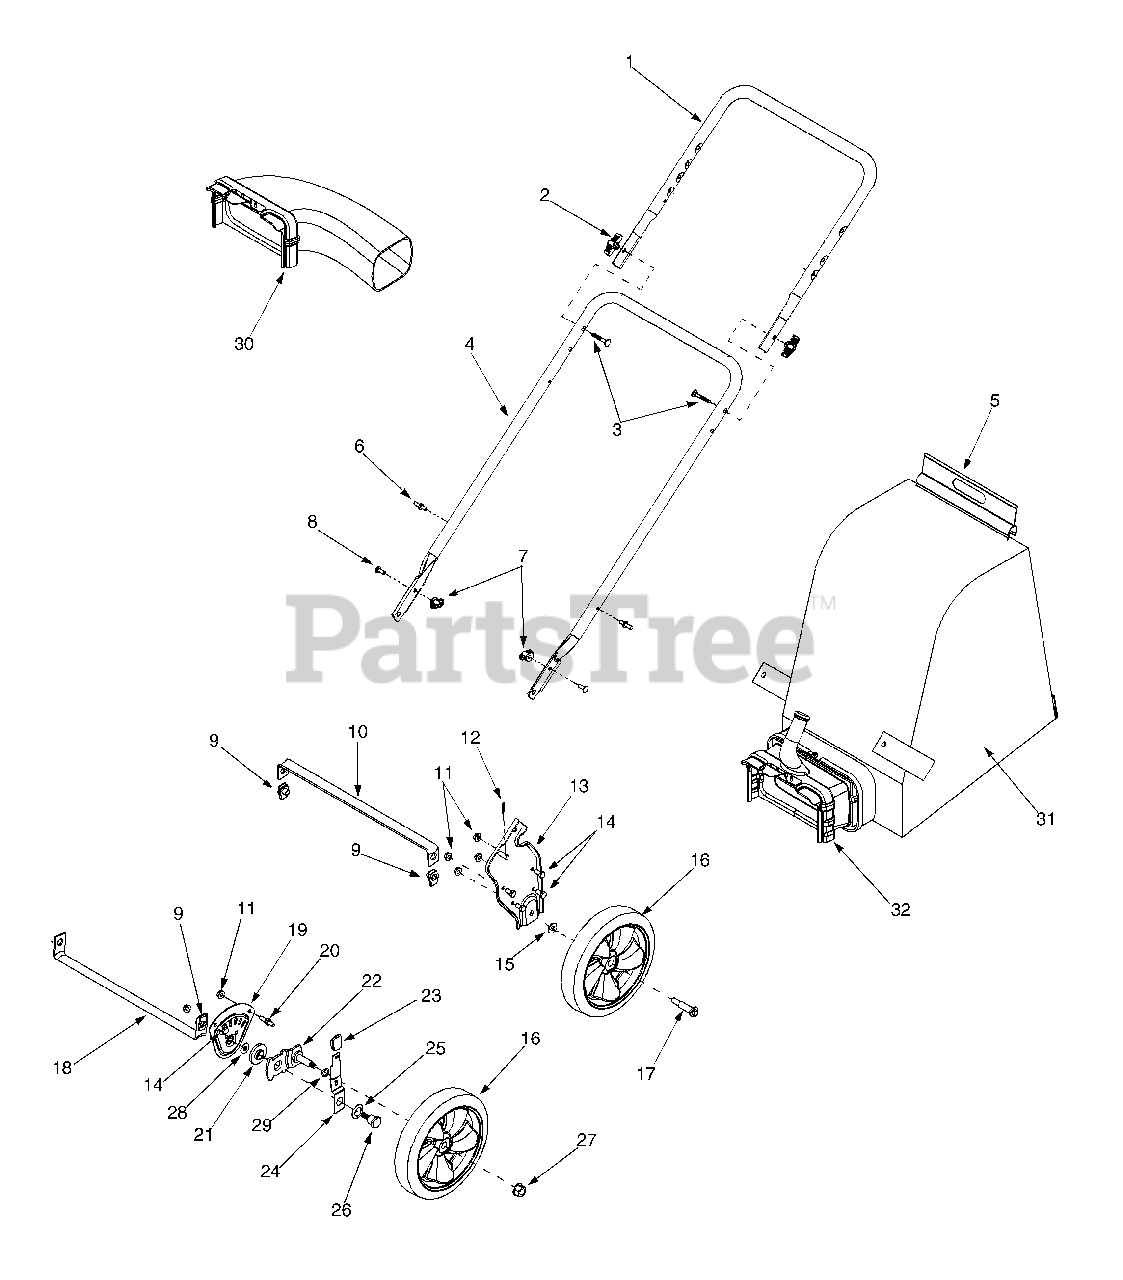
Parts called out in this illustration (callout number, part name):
3	Carriage Bolt
5	Bag Assembly
6	Studs
7	Wing Nut 1/4-20
8	Carriage Screw 1/4-20 x .75
9	Lock U-Clip Nut 3/8-16
12	Cotter Pin
14	Hex Cap Screw 5/16-18 x .625
15	Bell Washer.401 ID x .870 OD
16	Wheel 8 x 8.1
17	Shoulder Screw 3/8-16
21	Height Adjustment Bearing
22	Pivot Arm Assembly
23	Height Adjustment Knob
24	Spring Lever
25	Bell Washer .760 ID x .25OD
26	Shoulder Screw .750 ID x .625 OD
27	Flange Lock Nut 3/8-16
28	Thrust Washer .375 ID x .70 OD
29	Wave Washer .531 ID x .781 OD
30	Blower Chute Ass'y
31	Bag
32	Chute Assembly
